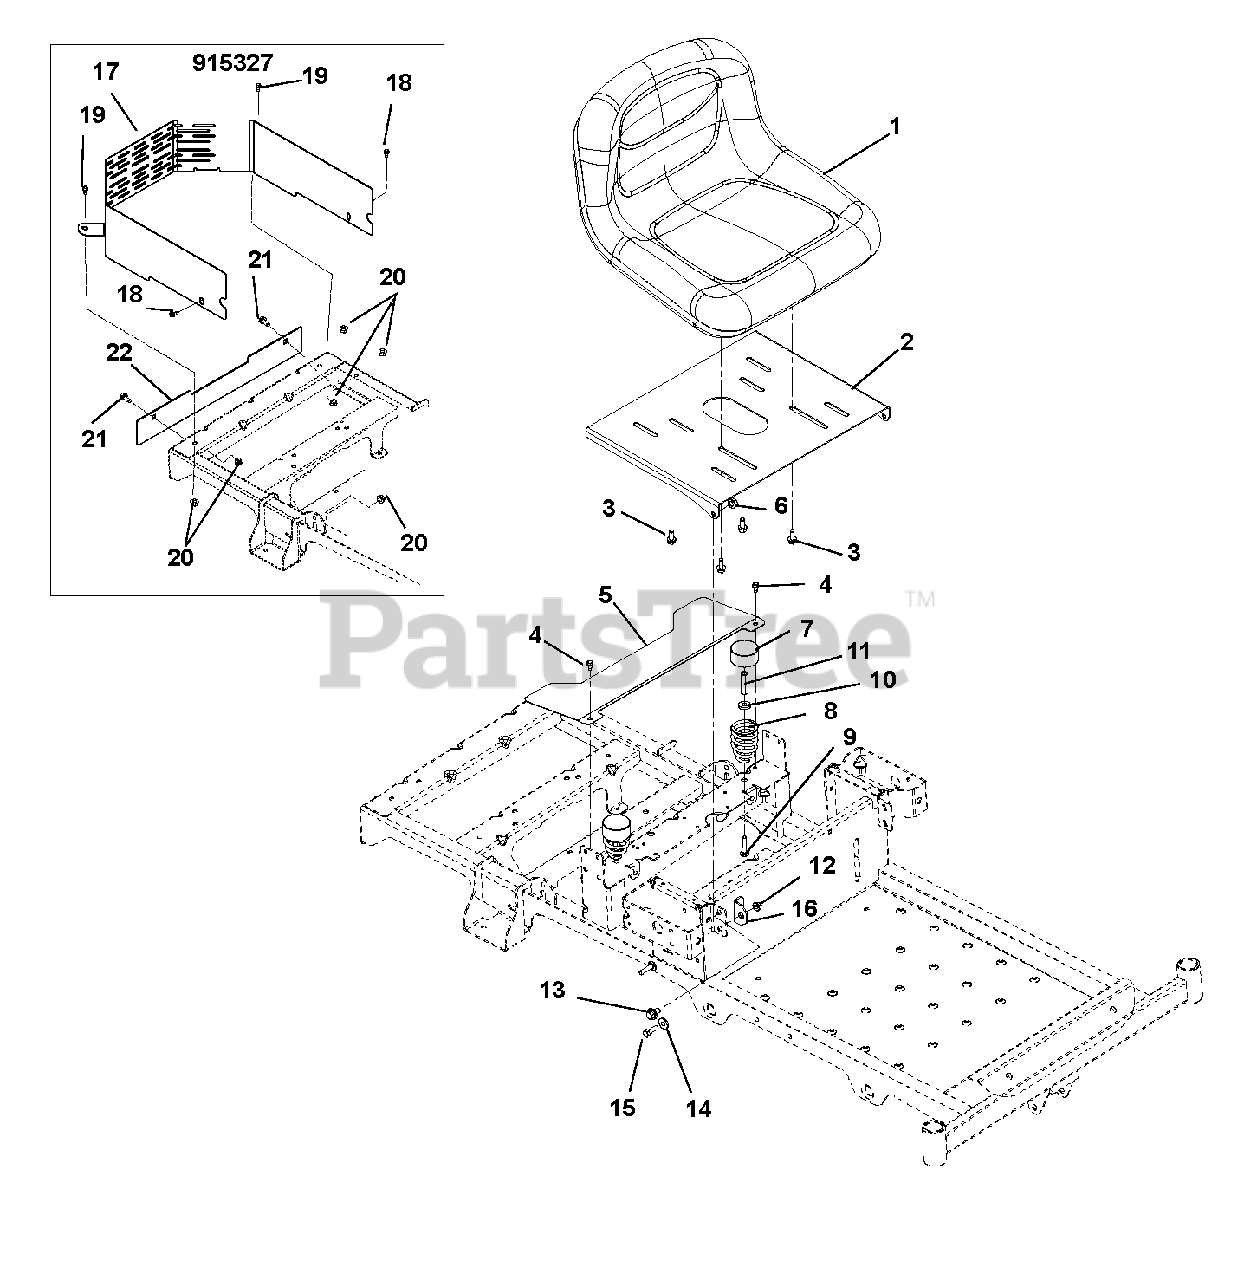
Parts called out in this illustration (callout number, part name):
1	Seat, 13 in Grey
2	Seat Plate
3	Bolt, Hex 5/16-18 x 3/4
4	Screw, Tapping .25-20 x .50 Hex Washer Head Thread
5	Cover, Zoom CE Fan
6	Nut, .38-16 Locking Top Flange
8	Spring, Seat
9	Bolt, Round Head Square Neck .31-18 x 1.50
10	Washer, Flat Steel .328 x .87 x .179
11	Nut, Coupling 5/16-18 x 1.75
12	Nut, 5/16-18 Flange Nyloc
13	Bolt, Shoulder .375-16 x .135
14	Bushing, Flange .325 x .499 x .26 x .88
15	Bolt, Hex .31-18 x 1.00
16	Bracket, Seat Stop
17	Wall, Reach-In Zoom CE
18	Bolt, Hex .38-16 x .75 Grade 5 YWCZ
19	Bolt, Hex .38-16 x 1.00 Grade 5 YWZC
20	Nut, Locking Center .38-16
21	Bolt, Round Head Square Neck .38-16 x .75 Grade 5 YWZC
22	Flange, Muffler Zoom CE
